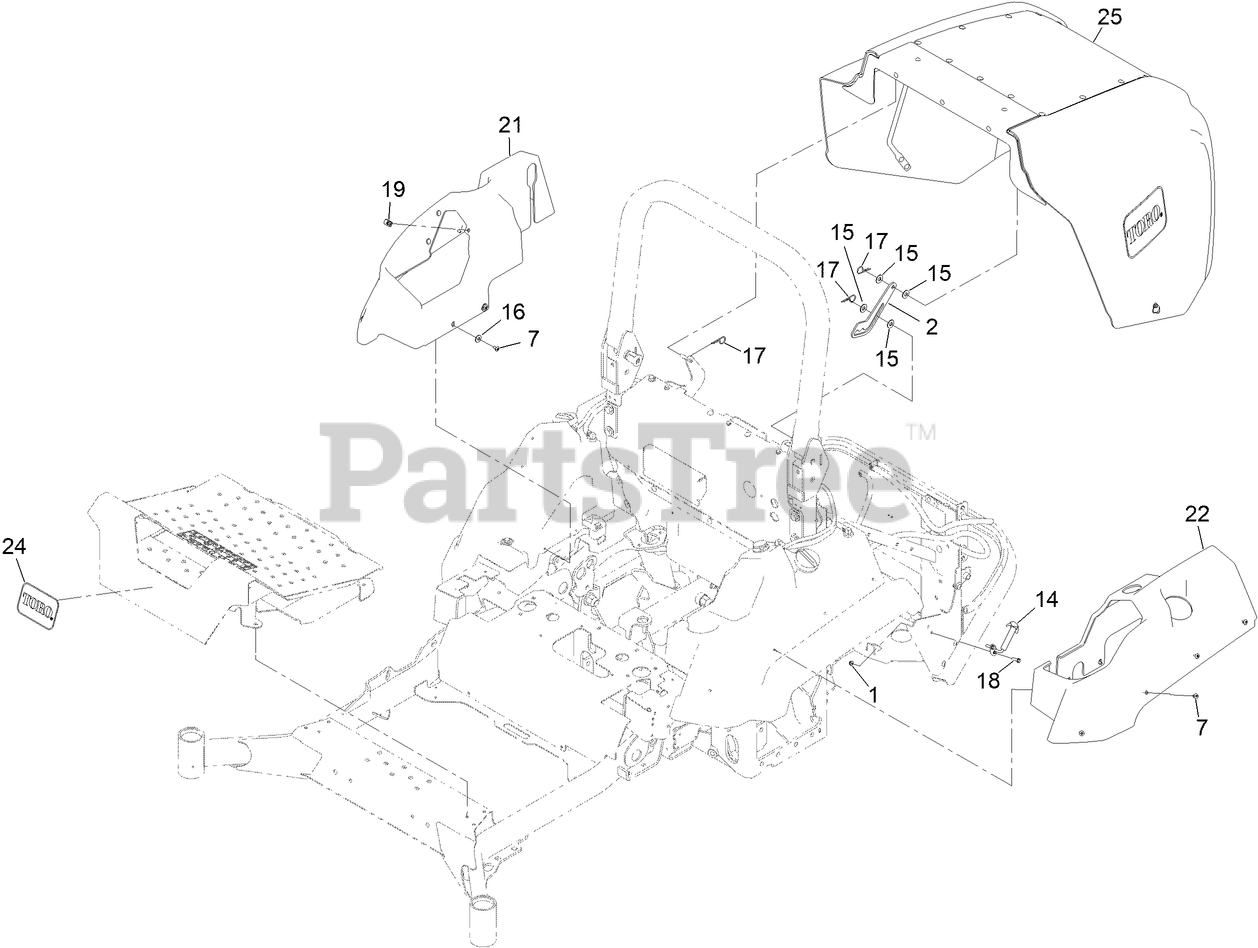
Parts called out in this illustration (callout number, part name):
1	NUT-HF
2	PROP-HOOD
7	SCREW-TORX
14	LATCH-HOOK
15	WASHER-FLAT
16	WASHER-FLAT
17	PIN-COTTER, HAIR
18	SCREW-HWH
21	COVER-TANK, RH
22	COVER-TANK, LH
24	DECAL
25	ASM, HOOD LZSD
